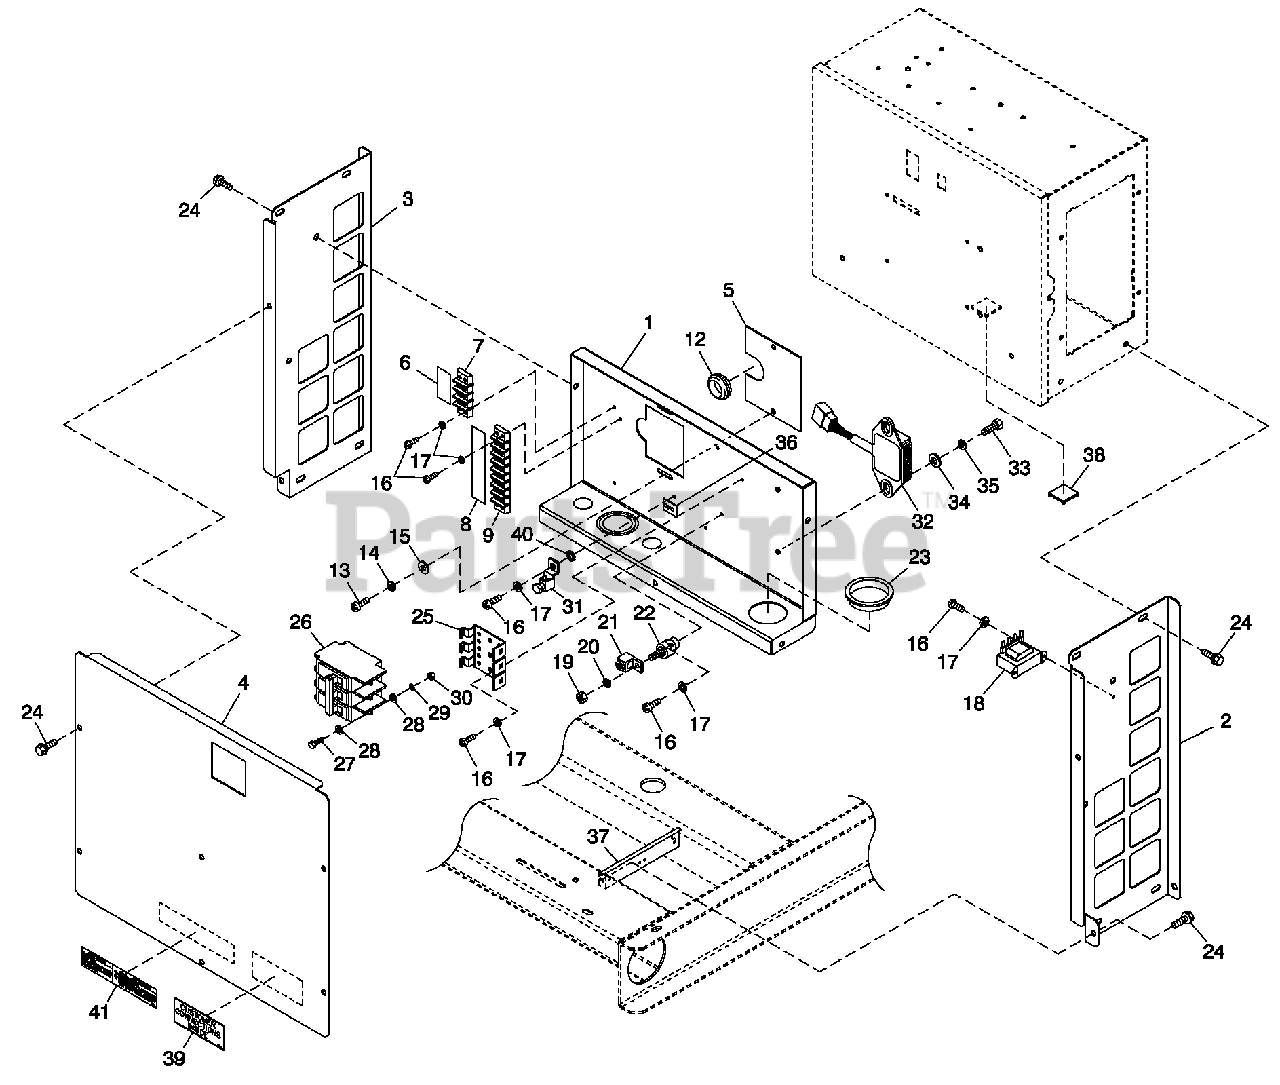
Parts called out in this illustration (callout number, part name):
1	BREAKER TRAY BACK/BOTTOM
2	SUPPORT CONTROL PANEL SIDE RH
3	SUPPORT CONTROL PANEL SIDE LH
4	COVER CIRCUIT BREAKER 2P
5	PLATE WIRE SNGL GALV
6	DECAL CUST CONN 120V UTILITY
7	BLOCK TERM 20A 6 X 3 X 1100V
8	DECAL UTIL SENSE/CUST CONN
9	BLOCK TERM 20A 8 X 6 X 1100V
12	GROMMET 1.25 X .25 X .75
13	SCREW HHTT M5-0.8 X 12 BP
14	WASHER LOCK M5
15	WASHER FLAT M5
16	SCREW PHTT M4-0.7 X 16 ZYC
17	WASHER LOCK #8-M4
18	XFMR DUAL 104V/16V (3 PHASE)
19	NUT HEX 3/8-16 STEEL
20	WASHER LOCK 3/8
21	LUG SLDLSS 350-#6 X 13/32 AL/CU
22	JUNCTION BLOCK 3/8-16
23	BUSHING SNAP SB-2000-26
24	SCREW HWHTF M6-1.0 X 16
25	BRKT CB MTG BACK 2P
26	CB 0125A 2P 240V S BQ2 LL ( 2 POLE)
31	LUG SLDLSS #6-14 X 13/64 CU
32	REGULATOR - DC ALT
33	SCREW HWHTF M6-1.0 X 16
34	WASHER FLAT 1/4-M6 ZINC
35	WASHER LOCK M6-1/4
36	DECAL GROUND LUG
37	BRACKET PANEL SUPPORT 1.5L C1
38	CABLE TIE MOUNT BLACK
39	DECAL CUSTOMER CONNECT INSIDE
40	WASHER SHAKEPROOF EXT #10 STL
41	DECAL DANGER HIGH VOLTAGE BI
